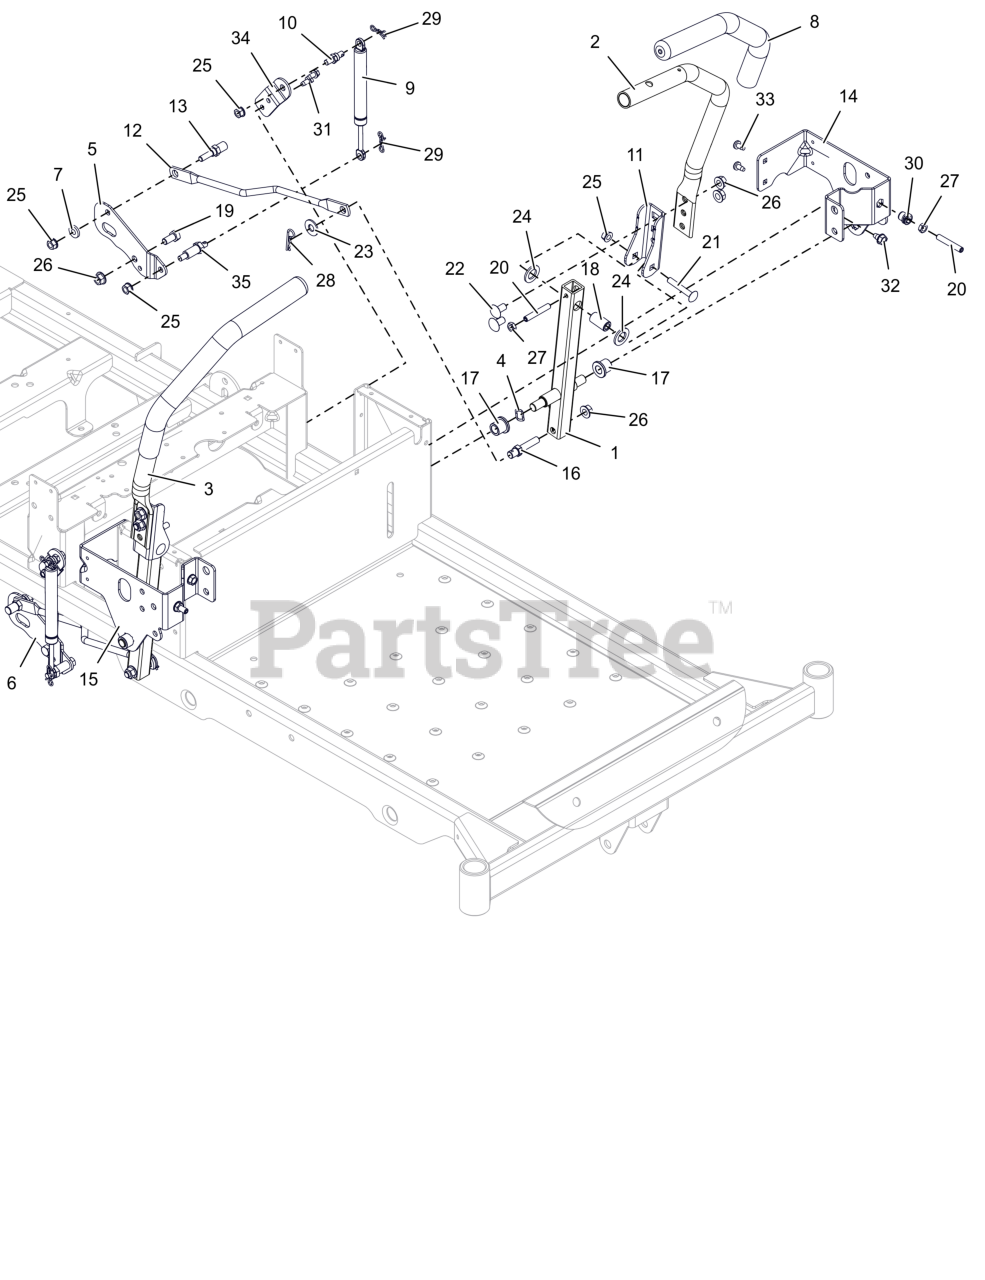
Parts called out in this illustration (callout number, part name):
1	WLDMT, LOWER CONTROL ARM (BLACK)
2	WLDMT, CONTROL HANDLE -LH (BLACK)
3	WLDMT, CONTROL HANDLE - RH (BLACK)
4	WAVE WASHER .531X.781X.125FH
5	PLATE, DAMPER RH
6	PLATE, DAMPER (LH)
7	BSHG-FLG .316X.430X.225X.750
8	GRIP, HANDLEBAR 15" FOAM
9	DAMPER, STRAIGHT MOUNT
10	COUPLER, DAMPER MOUNT
11	ARM, CONTROL -UPPER (BLACK)
12	LINKAGE, STEERING
13	STUD, STEERING LINK-REAR
14	BRKT, SPEED ADJ/SEAT PIVOT-LH (BLACK)
15	BRKT, SPEED ADJ/SEAT PIVOT-RH (BLACK)
16	STUD, STEERING LINK -FRONT
17	BHSG-FLG .500X.750X.750X.125
18	BSHG, -SLV .342 X .627 X 1.171
19	BLT,HEX .38-16X.75 G5 ZCC
20	SCR-SET, .312-18X2.000 SS
21	BLT, RHSSN .31-18X2.00 G5 ZCC
22	BTL,RHSSN .375-16 X 0.75 G5 FPB
23	WSHR,FLT .438X1.00X.083 ZCC
24	WSHR, FRICTION
25	NUT,LK-CTR-FLG .31-18 GF ZCC
26	NUT-LK-CTR-FLG .375-16 GF ZCC
27	NUT-JAM .312-18 G2 ZCC
28	PIN, HAIR #203 .09X1.50 ZCC
29	PIN, BOWTIE #72 ZCC
30	NUT, THREADED INSERT .31-18 ZC120
31	SCR-TAP .25-20X.50 HWH ZCC
32	SCR,TAP .312-18X.50 HWH TR ZCC
33	SCR, TAP .25-20X.5 PHD TRX ZCC
34	PLATE, DAMPER TOP MOUNTING (BLACK)
35	COUPLER, DAMPER MOUNT (LOWER)
